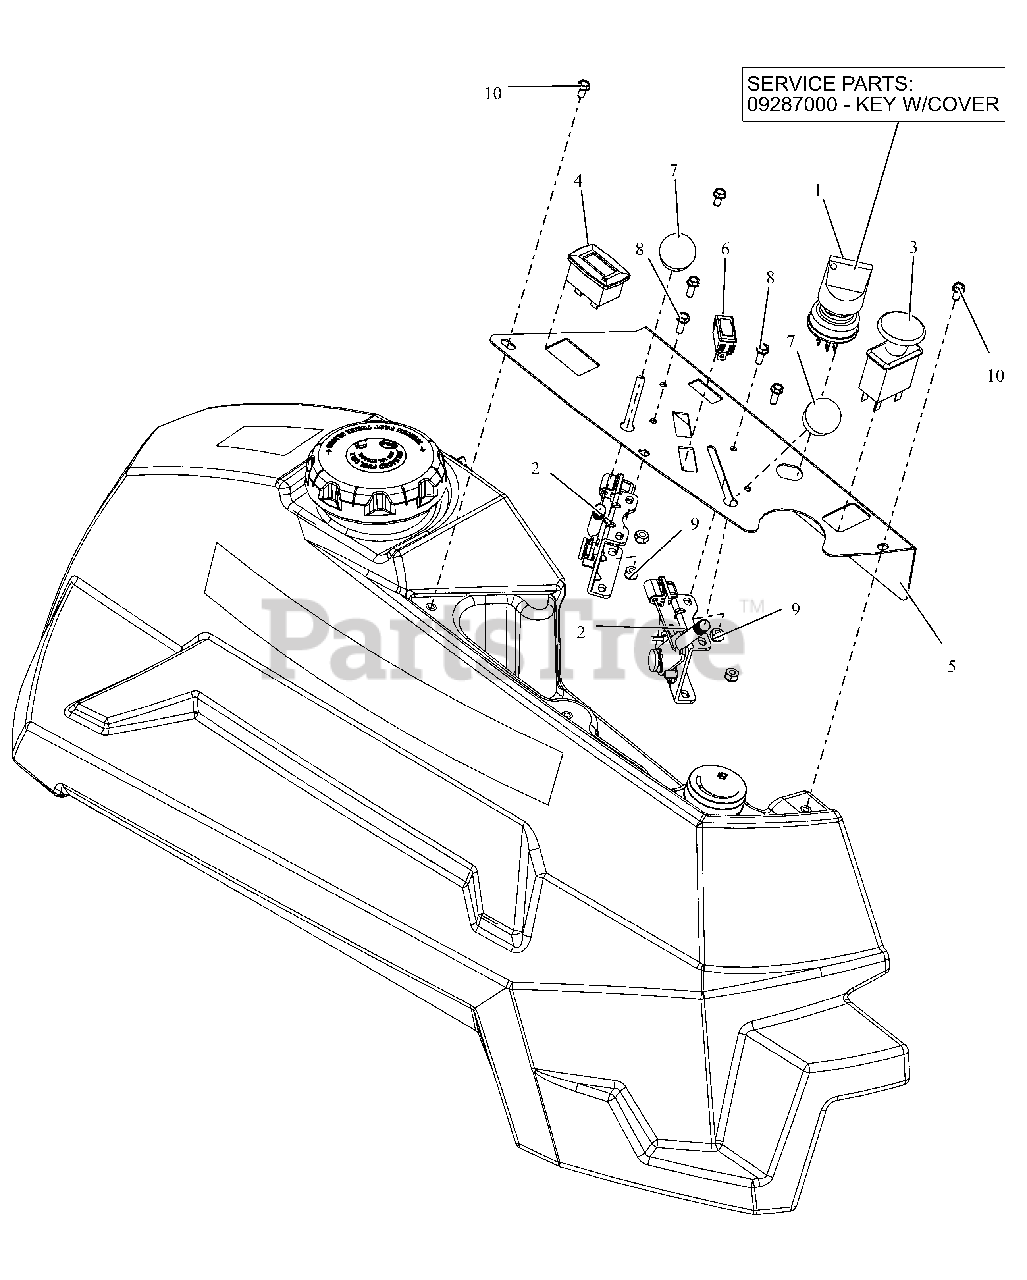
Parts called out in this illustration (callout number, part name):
1	SWITCH, IGNITION
1	KEY, W/ SHIELD
2	CABLE, PRO-CTRL 35.50"
3	SWITCH, CLUTCH
4	METER, HOUR W/MAINTENANCE
5	PT400 CONTROL PANEL - RED
6	LIGHT, INDICATOR (RED)
7	KNOB-CONTROL-BLACK .38-16X.50
8	BLT, HWH #10-24X.50 ZCC
9	NUT-LK-NYL #10-24 G2 ZCC
10	SCR-MCH 10-24X.38 HWHSTAINLESS
